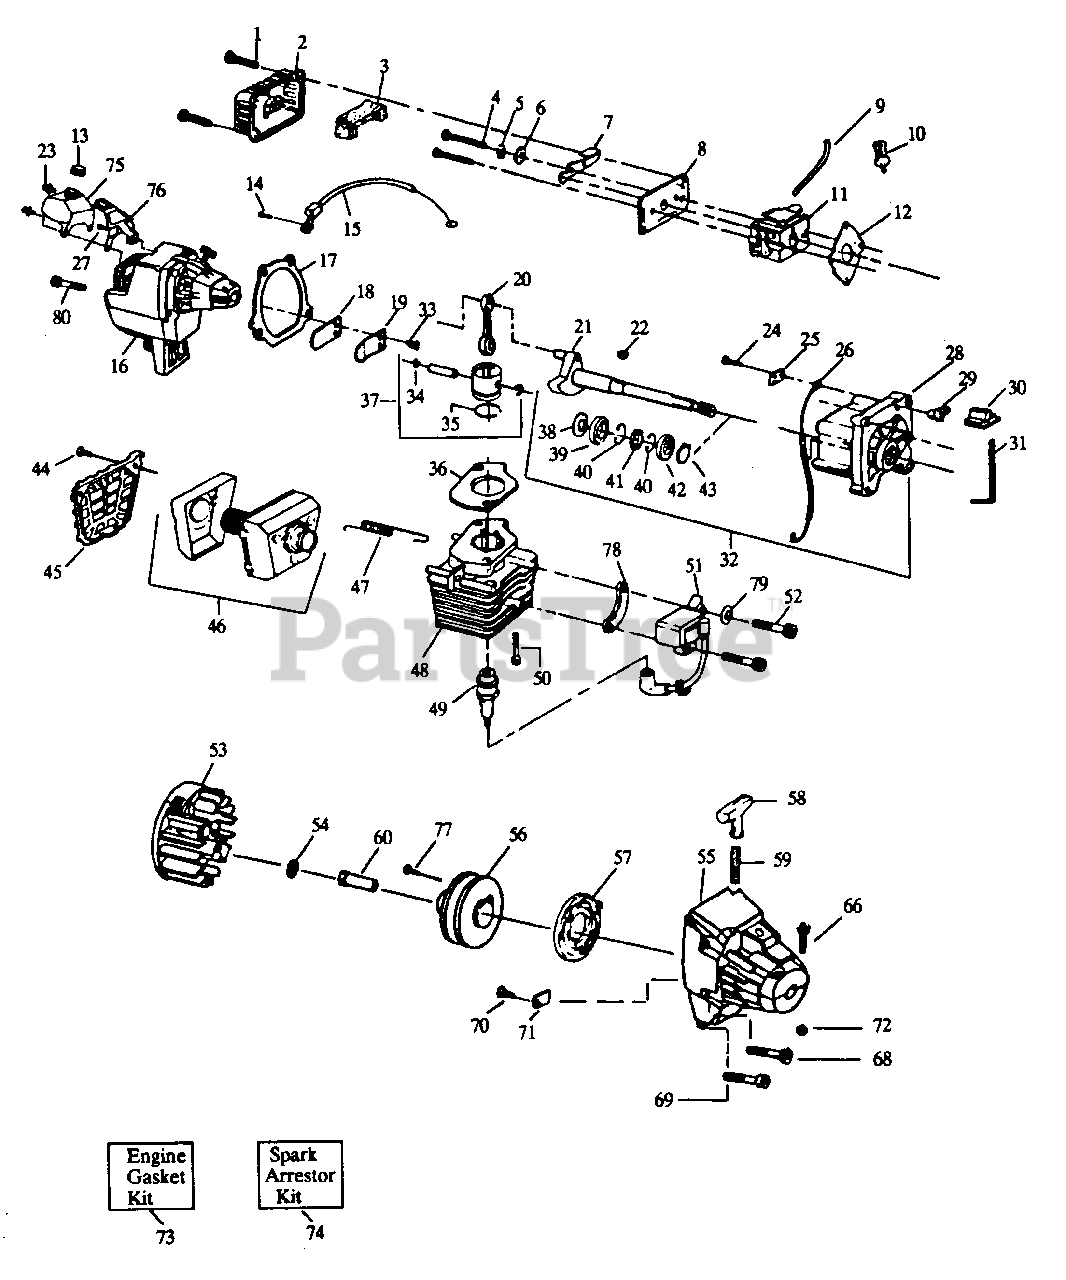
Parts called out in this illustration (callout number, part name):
2	Air Filter Cover
3	Air Filter
5	Spacer
6	Wave Washer
7	Choke Shutter
8	Air Filter Plate
9	Fuel Line
10	Fuel Pick-up Ass'y.
11	Carburetor
12	Carburetor Gasket
13	Fuel Cap Ass'y.
15	Throttle Cable Ass'y.
17	Crankcase/Shroud Gasket
19	Reed Stop
20	Connecting Rod Ass'y.
21	Crankshaft Ass'y.
22	Flywheel Key
25	Switch Insulator
26	Lead Wire
27	Screw
28	Crankcase Ass'y. (Inc.39-42)
29	Switch Ramp
30	Switch Button
31	Switch Spring
32	Crankcase & Crankshaft Ass'y (Inc.21,28,38, 43)
34	Piston Pin Retainer
35	Piston Ring
36	Cylinder Gasket
37	Piston Kit (Inc.34,35 & pin)
39	Inner Bearing
40	Retaining Ring
41	Crankshaft Seal
42	Outer Bearing
43	Crankshaft Retaining Ring
45	Muffler Guard
46	Muffler Kit
47	Muffler Attachment Spring
48	Cylinder
49	Spark Plug
51	Ignition Module Kit
53	Flywheel Ass'y.
55	Fan Housing
56	Starter Pulley
57	Starter Spring
58	Starter Handle
59	Rope Kit
60	Drive Coupling
71	Retainer
73	Engine Gasket Kit
74	Spark Arrestor Kit
75	Fuel Tank Ass'y.
76	Fuel Tank Mtg. Bracket
77	Screw
